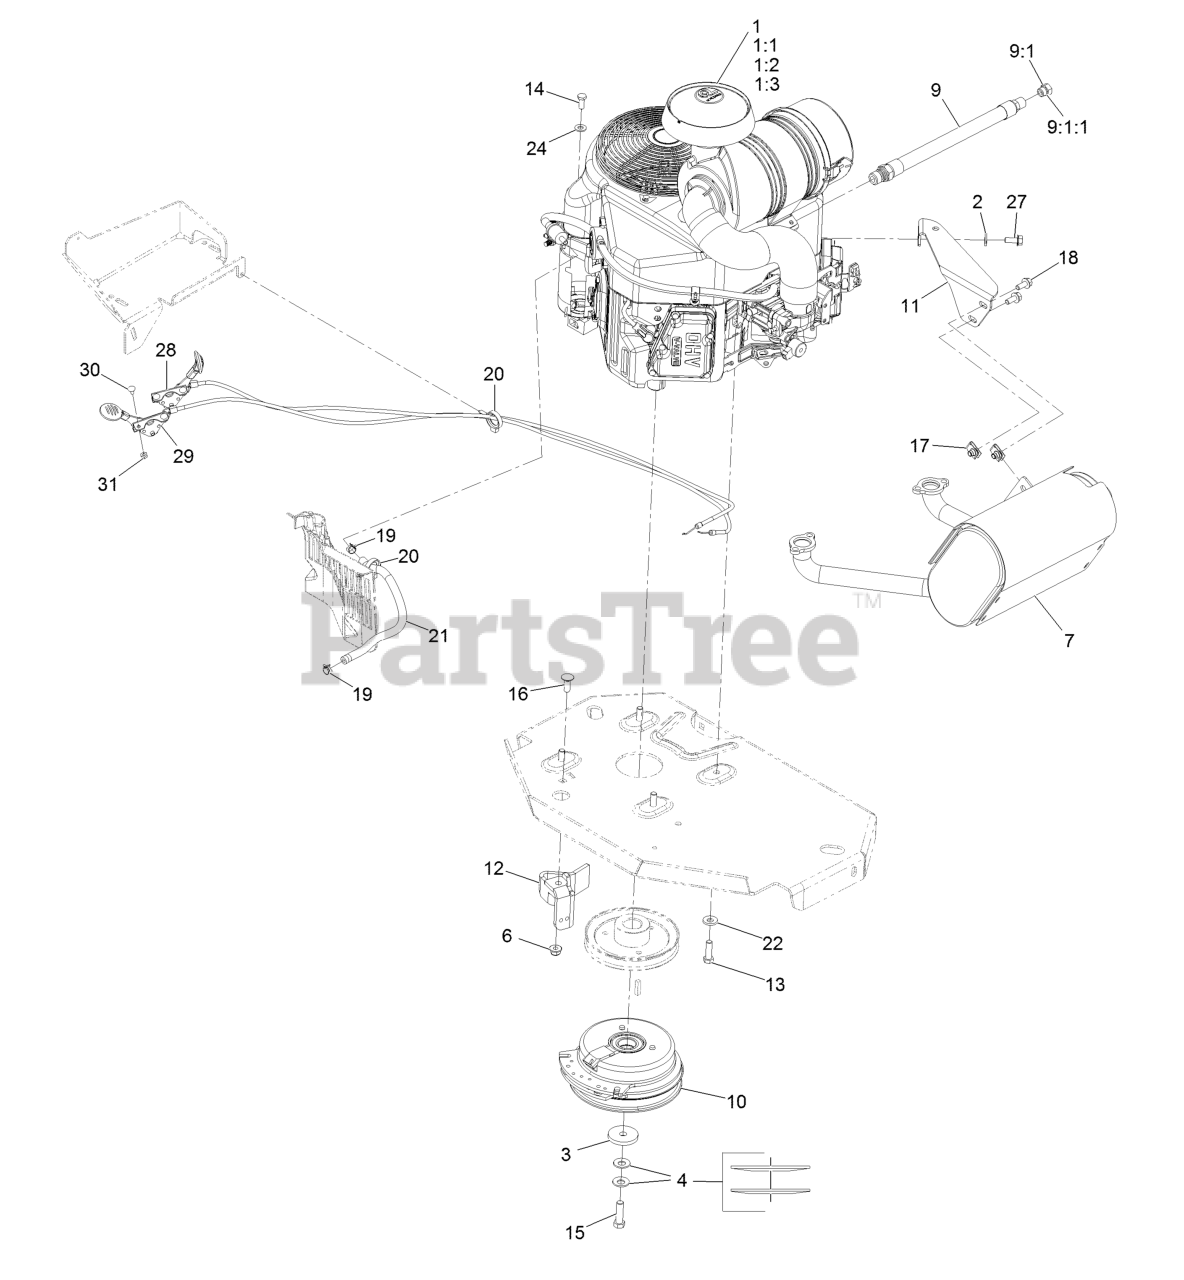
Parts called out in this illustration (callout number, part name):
1:1	Kawasaki 49065-7007 Engine Oil Filter
1:2	Kawasaki 11013-7044 Engine Air Filter
1:3	Kawasaki 11013-7045 Safety Filter
2	Washer-Spring Disc 5/16
3	Washer-Clutch
4	Washer-Spring Disc 7/16
6	Nut-Nyloc 3/8-16 Flg
7	Muffler
9	Asm-Hose Oil Drain W/Plug
9:1	Plug-W/O-Ring
9:1:1	O-Ring
11	Bracket-Muffler
12	Clutch-Anchor
13	Screw-HH 3/8-16 X 1 1/4
14	Screw-HH M8-1.25 X 20Mm
15	Screw-HH 7/16-20 X 1 1/2 W/Loctite
16	Bolt-Carriage 3/8-16 X 1
18	Screw-HH Flg 5/16-18 X 3/4
19	Clamp-Hose
20	Clamp-Hose
21	Hose-Fuel Line 15"
22	Washer-Spring Disc 3/8
27	Screw-HH M8-1.25 X 20Mm
28	ASM, Choke Cable
29	ASM,Throttle Cable
30	Bolt-Carriage #10-24 X 1/2
31	Nut-Nyloc #10-24
